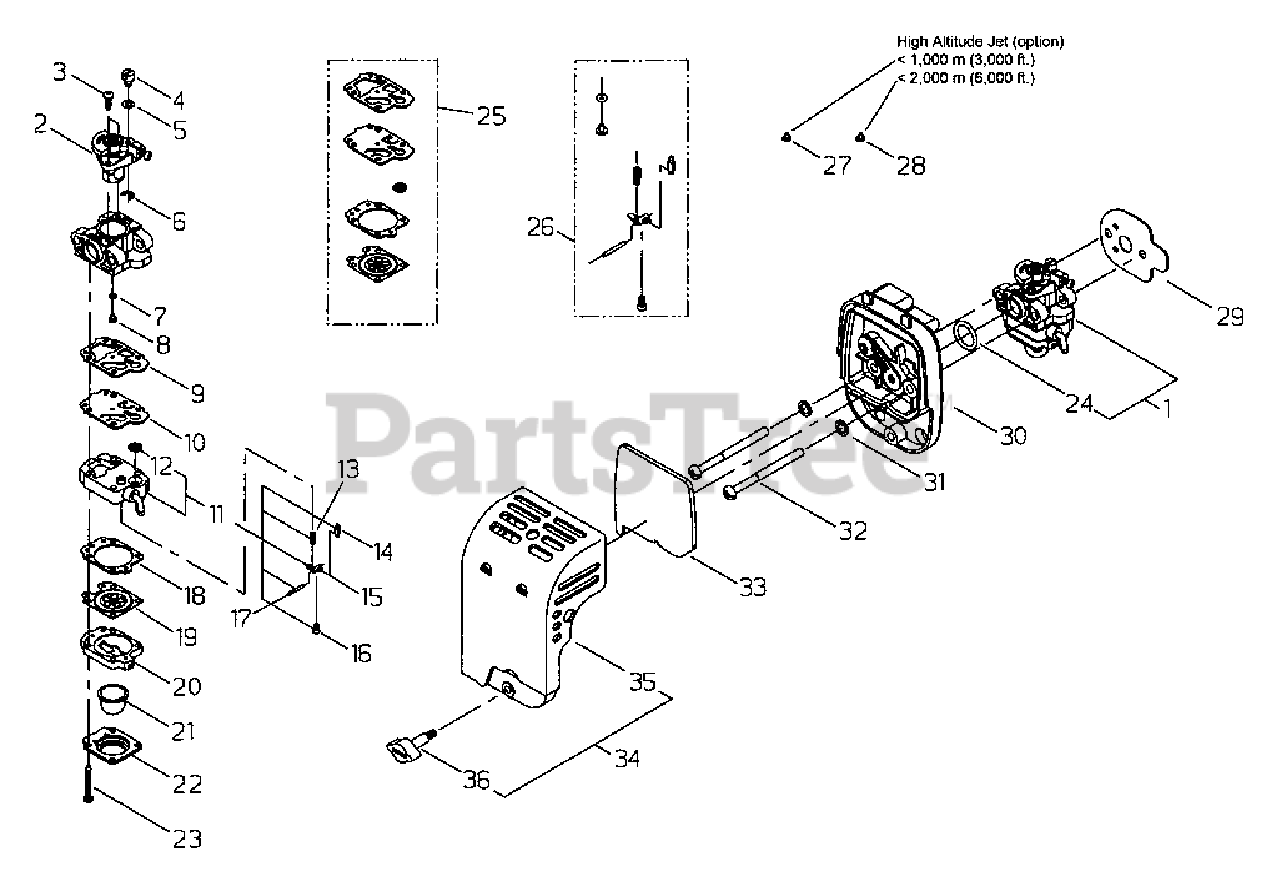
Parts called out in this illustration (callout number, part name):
1	CARBURETOR
2	VALVE ASSY, THROTTLE
3	SCREW, THROTTLE COLLAR
4	SWIVEL
5	WASHER
6	E-RING
7	GASKET, PUMP
8	JET, MAIN
9	GASKET, PUMP
10	DIAPHRAGM, PUMP
11	BODY ASSY, PUMP
12	SCREEN, FUEL INLET
13	SPRING, METERING LEVER
14	VALVE, INLET NEEDLE
15	LEVER, METERING
16	SCREW
17	PIN, METERING LEVER
18	GASKET, METERING DIAPHRAGM
19	DIAPHRAGM, METERING
20	BODY ASSY, PURGE
21	BULB, PURGE
22	RETAINER, PURGE BULB
23	SCREW
24	O-RING 15
25	GASKET / DIAPHRAGM KIT
26	VALVE KIT, INLET NEEDLE
27	JET, MAIN
28	JET, MAIN
29	GASKET, INTAKE
30	CASE ASSY, AIR FILTER
31	WASHER 5 MM
32	SCREW M5×60
33	FILTER, AIR
34	COVER ASSY, AIR FILTER
35	COVER, AIR FILTER
36	THUMBSCREW M5
